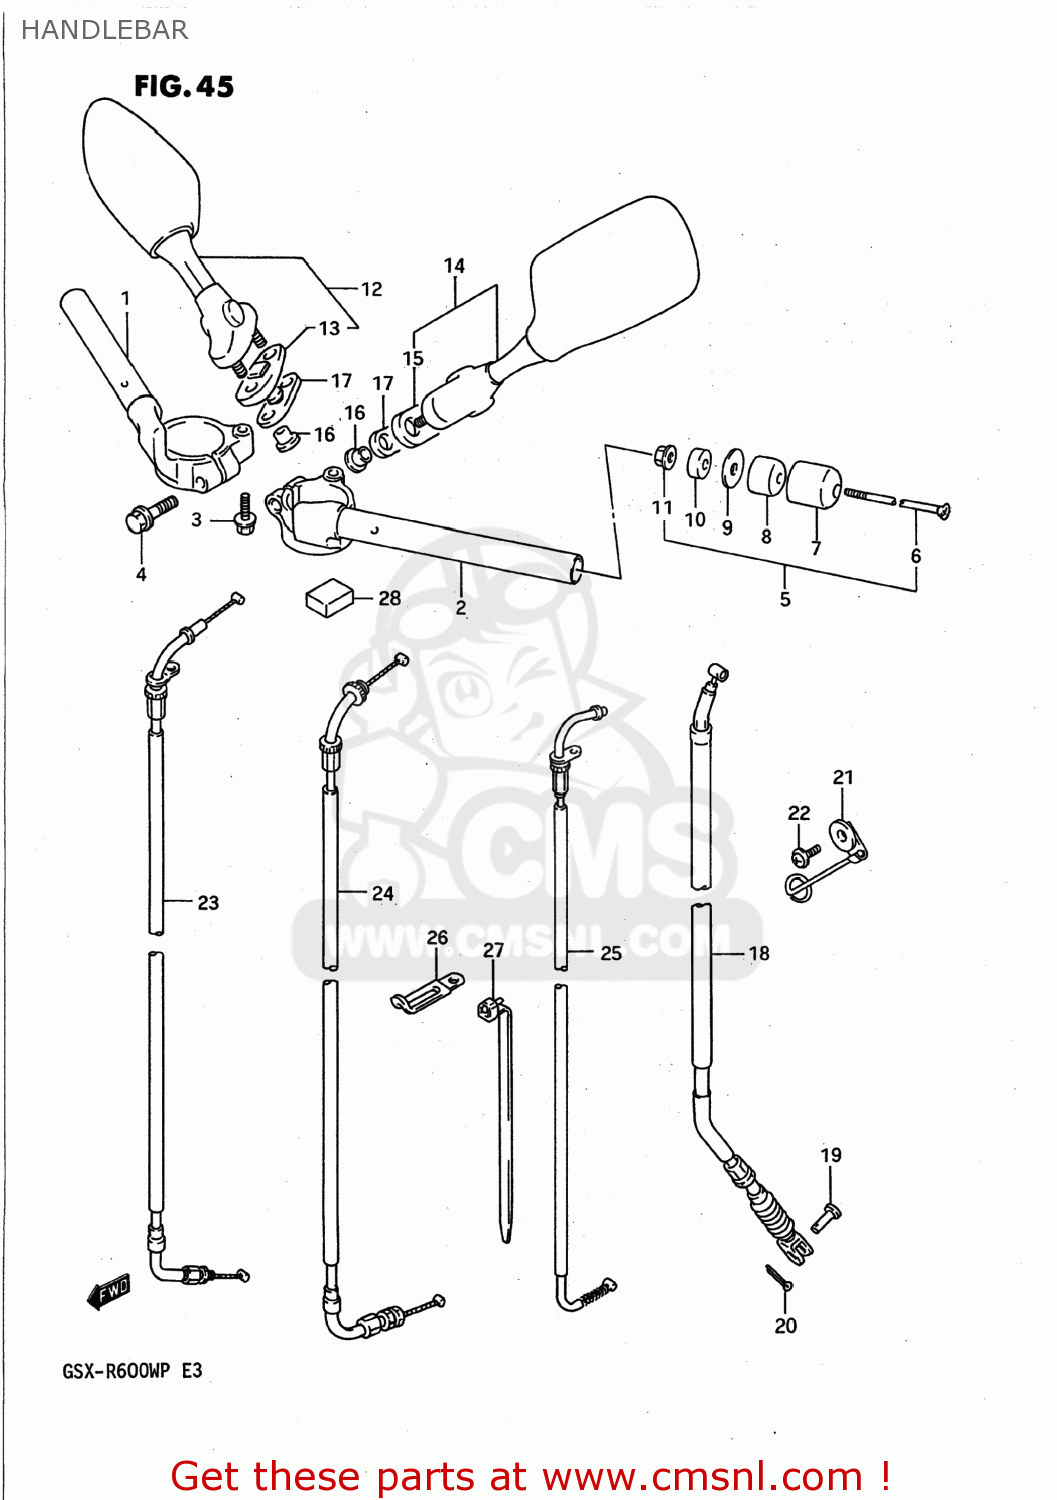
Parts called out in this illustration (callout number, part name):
1	HANDLEBAR,RIGHT
2	HANDLEBAR,LEFT
3	BOLT 6X20
4	BOLT
5	BALANCER SET,HANDLEBAR
6	SCREW 6X65
7	CAP,BALANCER
8	BALANCER,HANDLE
9	SPACER,BALANCER
10	EXPANDER,HANDLE BALANCER
11	NUT
12	MIRROR ASSY,RR VIEW,R
13	GASKET,RR VIEW MIRROR,R (NAS)
14	MIRROR ASSY,RR VIEW,L
15	GASKET,RR VIEW MIRROR,L (NAS)
16	NUT,RR VIEW MIRROR
17	CUSHION,RR VIEW MIRRORR
18	CABLE ASSY,CLUTCH
19	PIN(L:15)
20	PIN
21	GUIDE,DRAIN HOSE
22	SCREW
23	CABLE ASSY,THROTTLE NO.1
24	CABLE ASSY,THROTTLE NO.2
25	CABLE,STARTER
26	CLAMP
27	CLAMP(L:235)
28	CUSHION,FRAME COVER
